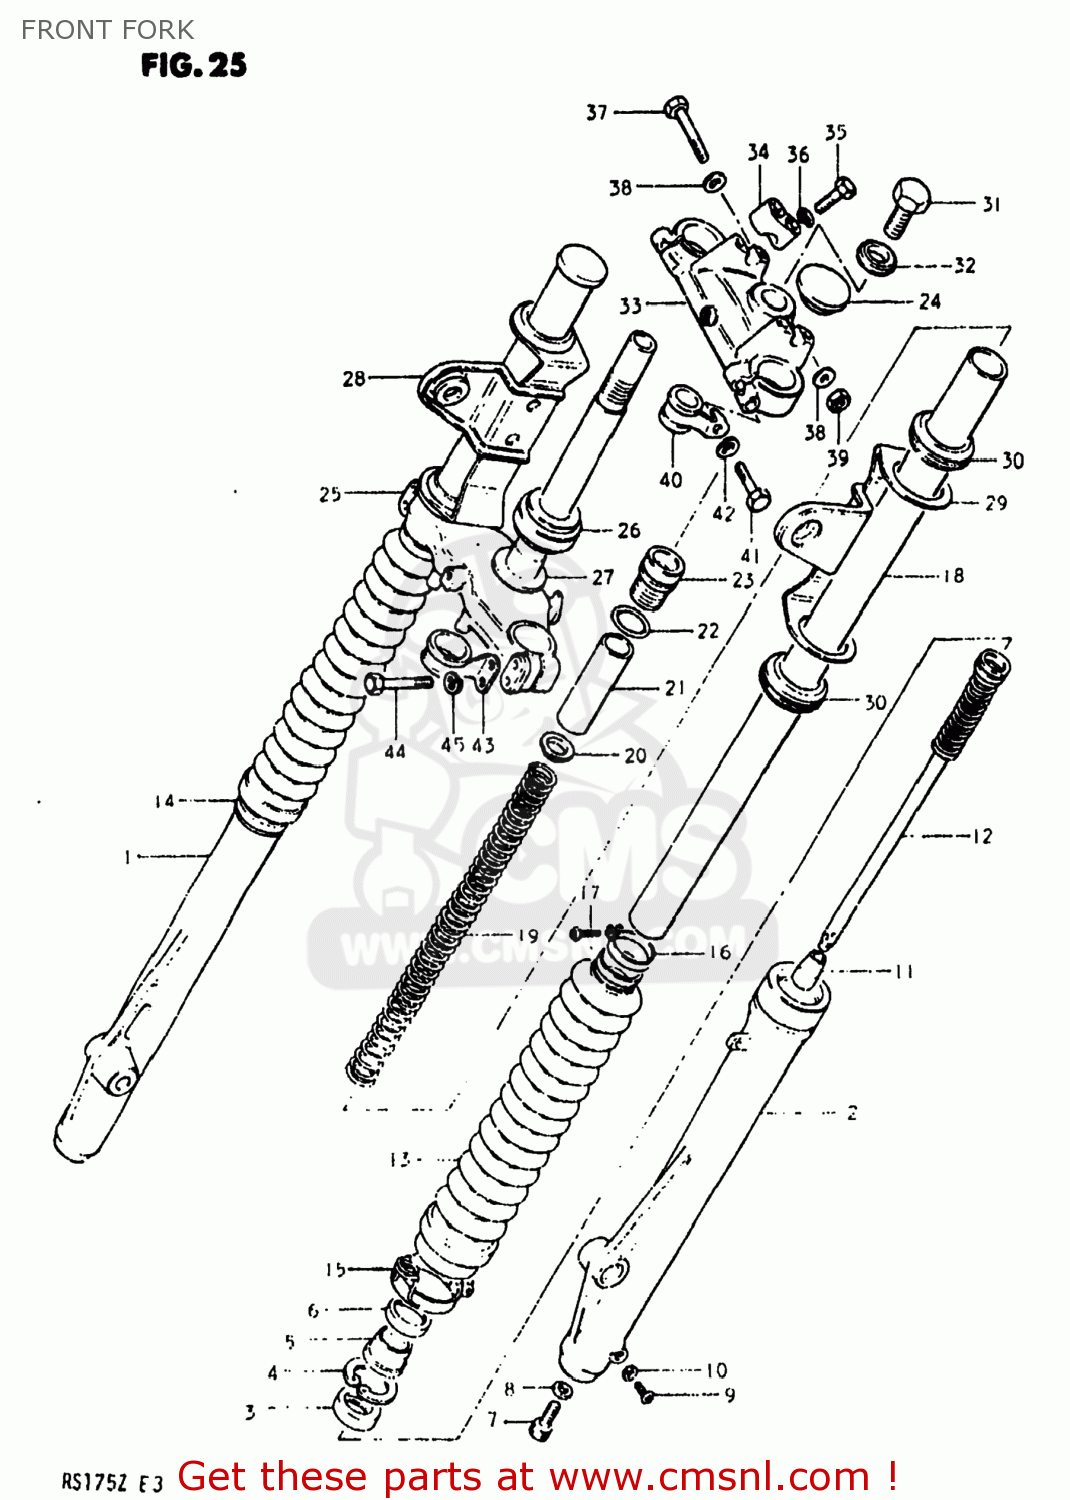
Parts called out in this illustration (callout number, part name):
1	TUBE,OUTER,RIGHT
2	TUBE,OUTER,LEFT
3	OIL SEAL,FRONT FORK
4	5
5	SEAL,DUST
6	CASE,DUST SEAL
7	BOLT,FORK CYLINDER(10X25)
8	GASKET (NAS)
9	SCREW
10	GASKET,DRAIN,PLUG (NAS)
11	PIECE,OIL LOCK
12	CYLINDER,FRONT FORK
13	BOOT
14	BAND,FRONT FORK COVER
15	BAND,FRONT FORK COVER
16	BAND,BOOT
17	SCREW
18	TUBE,FORK,INNER
19	SPRING
20	GUIDE,FRONT FORK SPRING C
21	COLLAR,SPRING
22	O RING
23	CAP,FORK INNER TUBE
24	CAP,FRONT FORK
25	STEM,STEERING
26	BEARING
27	WASHER,THRUST
28	BRACKET,HEADLAMP,RIGHT
29	BRACKET,HEADLAMP,LEFT
30	CUSHION,HEADLAMP BRACKET
31	BOLT
32	WASHER
33	HEAD,STEERING STEM
34	HOLDER,HANDLEBAR
35	BOLT
36	LOCK WASHER
37	BOLT 8X50
38	WASHER
39	NUT
40	GUIDE,CABLE
41	BOLT
42	LOCK WASHER
43	CLIP,CABLE
44	BOLT 8X45
45	LOCK WASHER
